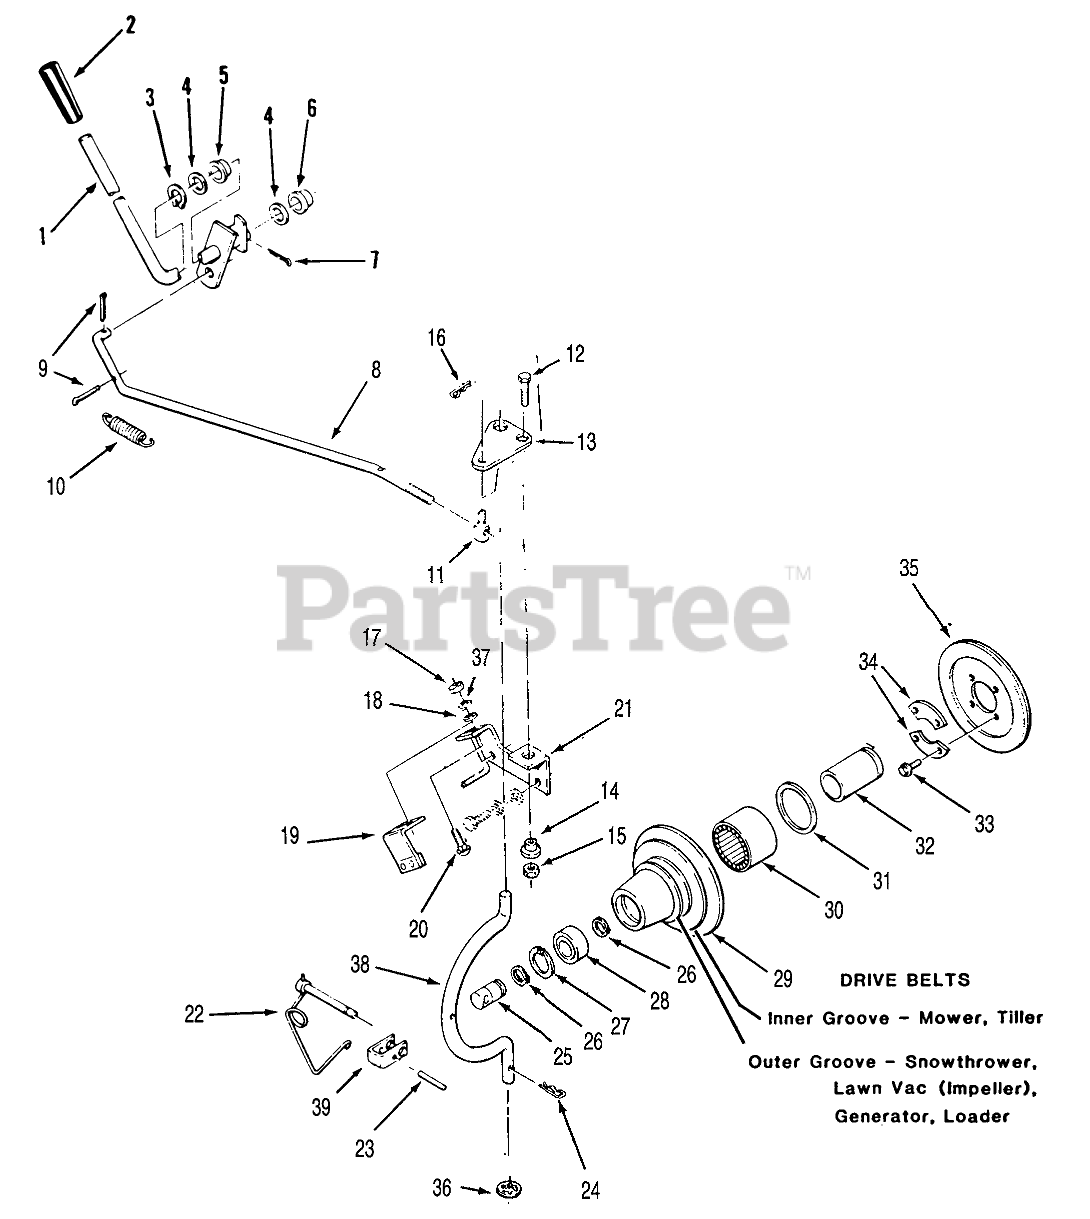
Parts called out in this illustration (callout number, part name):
1	ASSY PTO CLUTCH LEVE
2	GRIP
3	Grip Ring
4	SHIM-WASHER
5	BUSHING-NYLINER
6	NYLINER BUSHING
7	Pop Rivet
8	ROD-PTO CLUTCH
9	Pop Rivet
10	SPRING
11	TRUNNION
12	BOLT
13	PLATE
14	SPACER-LIFT LINK
15	NUT
16	Hairpin Cotter
17	Nut
19	ASM-Bracket
20	Bolt-Carriage
21	BRACKET WA ENG. B
22	LOCKING PIN ASM
24	Hairpin Cotter
25	SHAFT-PTO
26	RING-SNAP, EXTERNAL
27	Ring-Snap
28	BEARING-BALL
29	Housing-Clutch
30	BRG-NEEDLE OPEN END
31	SEAL-OIL
32	RACE-BEARING
33	H H C S
34	RETAINER
35	Facing-Clutch
36	RING-REINFORCED CIRC
37	Washer
38	ROD-HOUSING
39	CLEVIS
